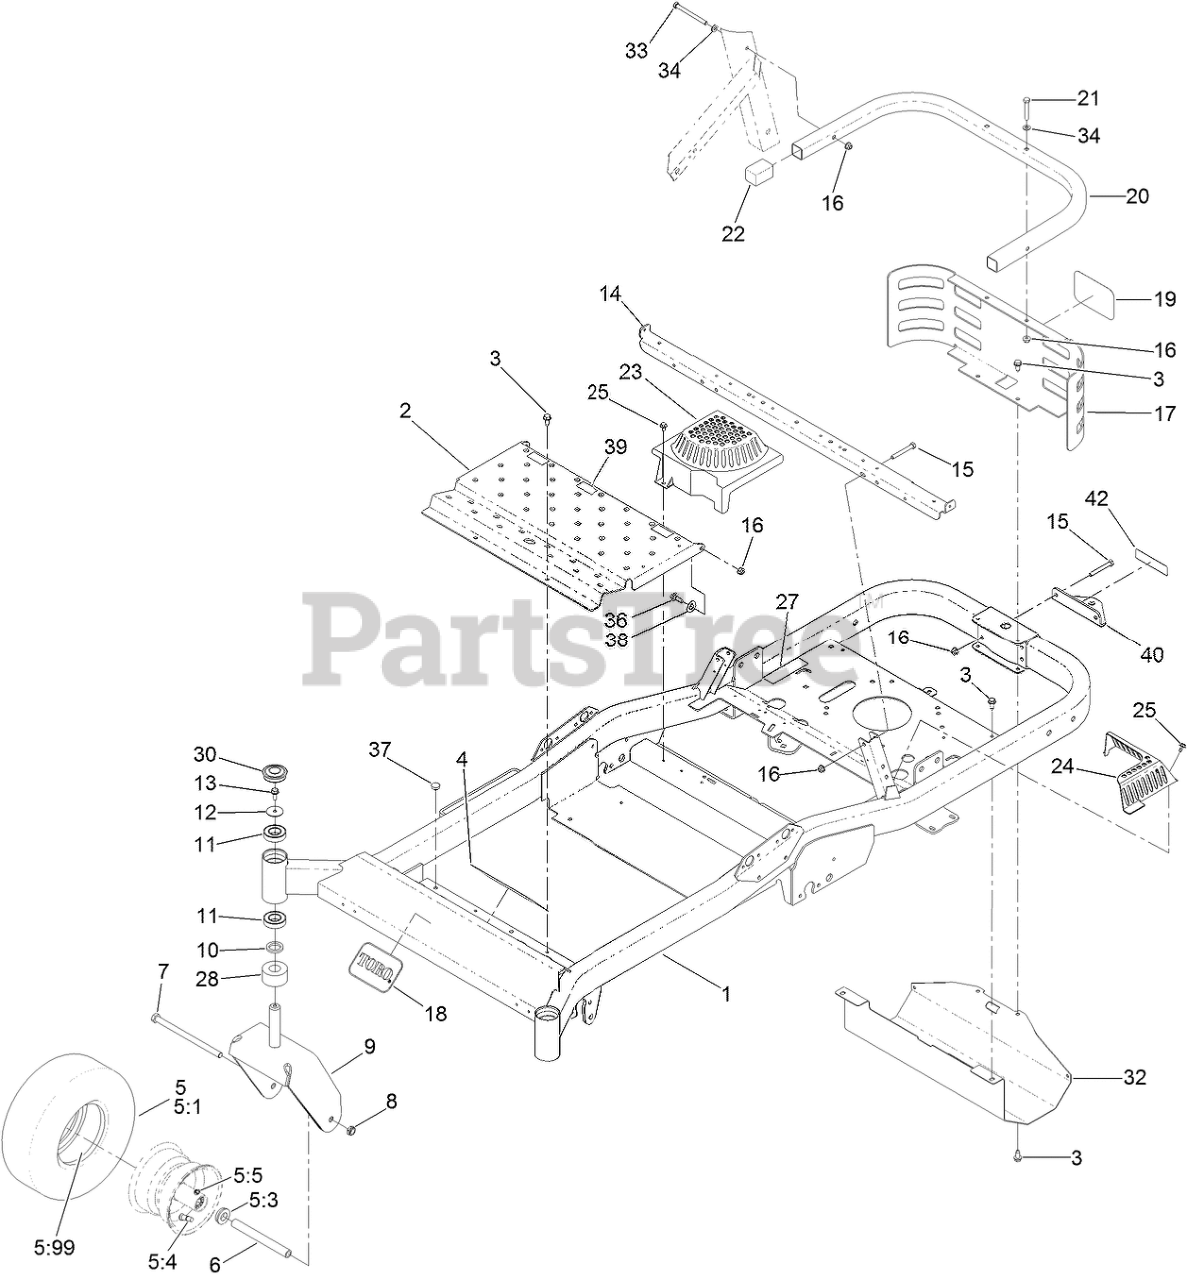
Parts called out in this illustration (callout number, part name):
1	FRAME ASM
2	PAN-FLOOR
3	SCREW-HWHTF
4	DECAL-DANGER
5	TIRE AND WHEEL ASM
5:1	TIRE-13 INCH SMOOTH
5:3	BUSHING-FLANGE
5:4	STEM-VALVE
5:5	FITTING-GREASE
5:99	TUBE-INNER
6	SPANNER
7	SCREW-HH
8	NUT-LOCK, NI
9	FORK-CASTER
10	WASHER-THRUST
11	BEARING-BALL
12	WASHER-FLAT
13	SCREW-HHF
14	SUPPORT-SEAT
15	SCREW-HH
16	NUT-HF, NI
17	GUARD-REAR
18	DECAL
20	TUBE-GUARD
21	SCREW-HH
23	COVER-FAN, RH
24	COVER-FAN, LH
25	SCREW-HHFTF
27	DECAL-EMISSIONS
28	SPACER-CASTER
30	CAP-GREASE
32	SHIELD-HEAT
33	SCREW-HH
34	WASHER-PLAIN
36	SCREW-SHOULDER
37	BUMPER
38	WASHER-TEFLON
39	PAD-RUBBER
40	BRACKET-HITCH
